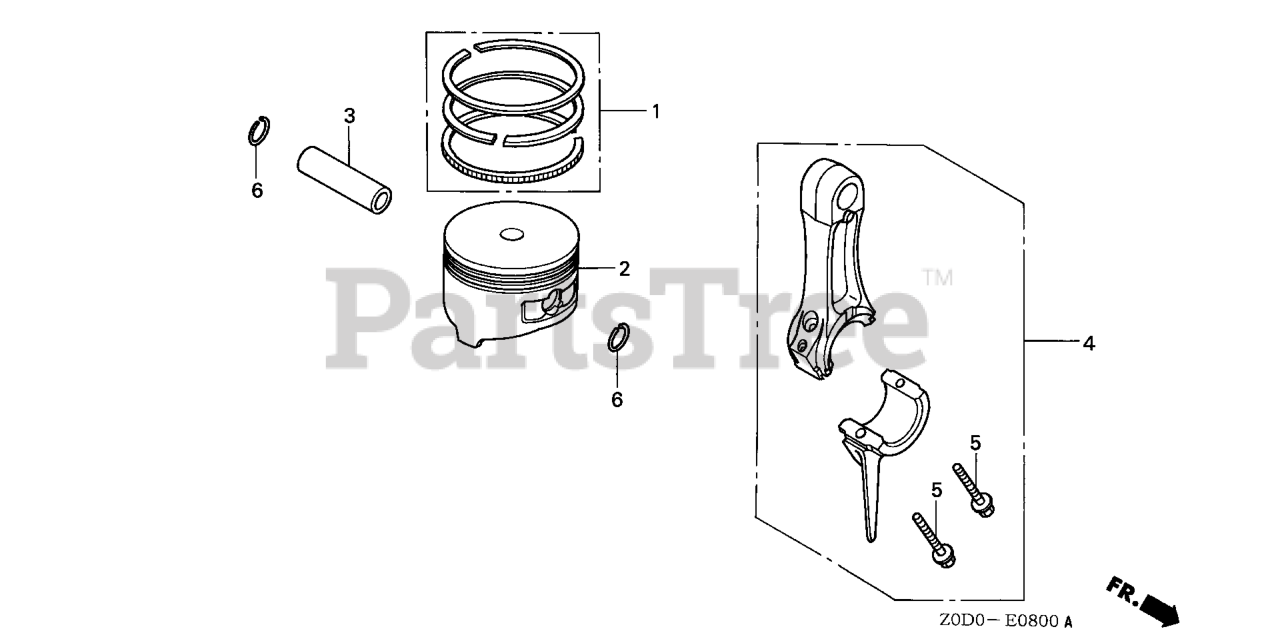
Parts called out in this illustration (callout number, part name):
1	RING SET, PISTON
3	PIN, PISTON
4	ROD ASSY., CONNECTING
4	ROD ASSY., CONNECTING (UNDER SIZE)
5	BOLT, CONNECTING ROD
6	CLIP, PISTON PIN (13MM)
